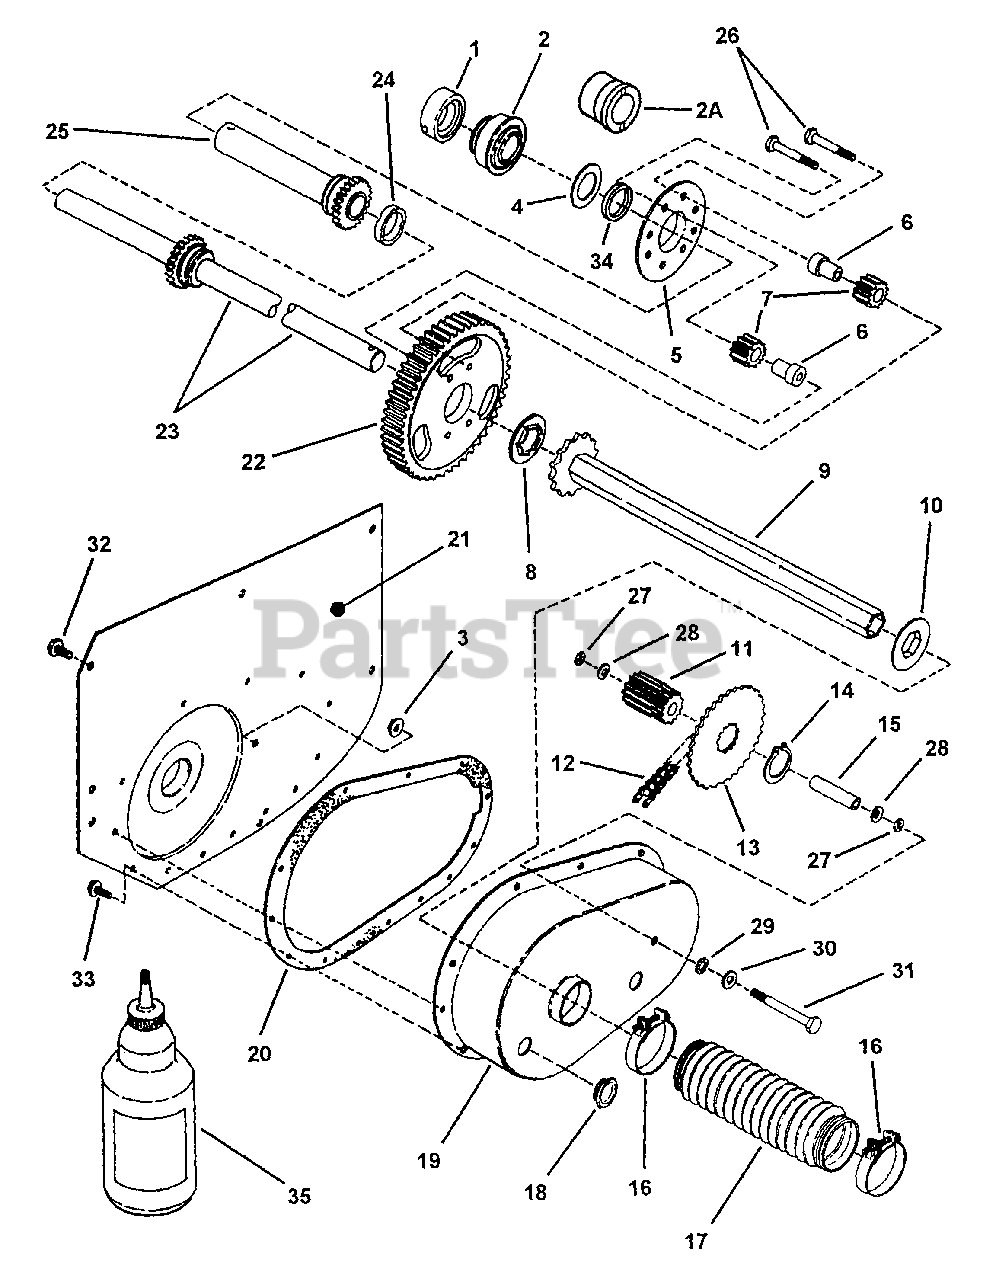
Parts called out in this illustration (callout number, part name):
1	COLLAR, Lock
2	BALL BEARING, Axle
2A	BEARING, Axle
3	NUT, 5/16-24 Hex Flange Lock
4	WASHER, Thrust
5	PLATE, Differential
6	SPACER, Pinion
7	GEARS, Differential Pinion
8	WASHER, Thrust
9	ASSEMBLY, Drive Hex Tube
10	WASHER, Hex Nylon Splash
11	GEAR, 11 Teeth 10 Pitch
12	CHAIN, 46 Pitch (#35)
13	SPROCKET
14	RING, External Retaining
15	SPACER
16	CLAMP, Boot, 2"
17	BOOT, Oil Seal
18	PLUG, Oil Fill & Check
19	CASE, Transmission
20	GASKET, Transmission Case
21	FENDER, Right Hand (2.498" ID Hole)
21	FENDER, Right Hand (1.62" ID Hole)
22	GEAR, 63 Teeth-10 Pitch
23	AXLE, Long
24	SPACER, Differential (1.25" ID x .425 Wide)
25	AXLE, Short
26	SCREW, 5/16-24 x 1-5/8" Hex Cap Special Lock
27	O-RING, 5/16"
28	WASHER, 5/16" Belleville
29	WASHER, 5/16" External Tooth Lock
30	WASHER, 5/16" Flat
31	BOLT, 5/16-24 x 2-5/8" Idler
32	SCREW, 5/16-18 x 5/8" Hex Washer Self-Tap
33	SCREW, 1/4-20 x 5/8" Hex Washer Self-Tap
34	SPACER, Short Axle
35	GREASE, Transmission
